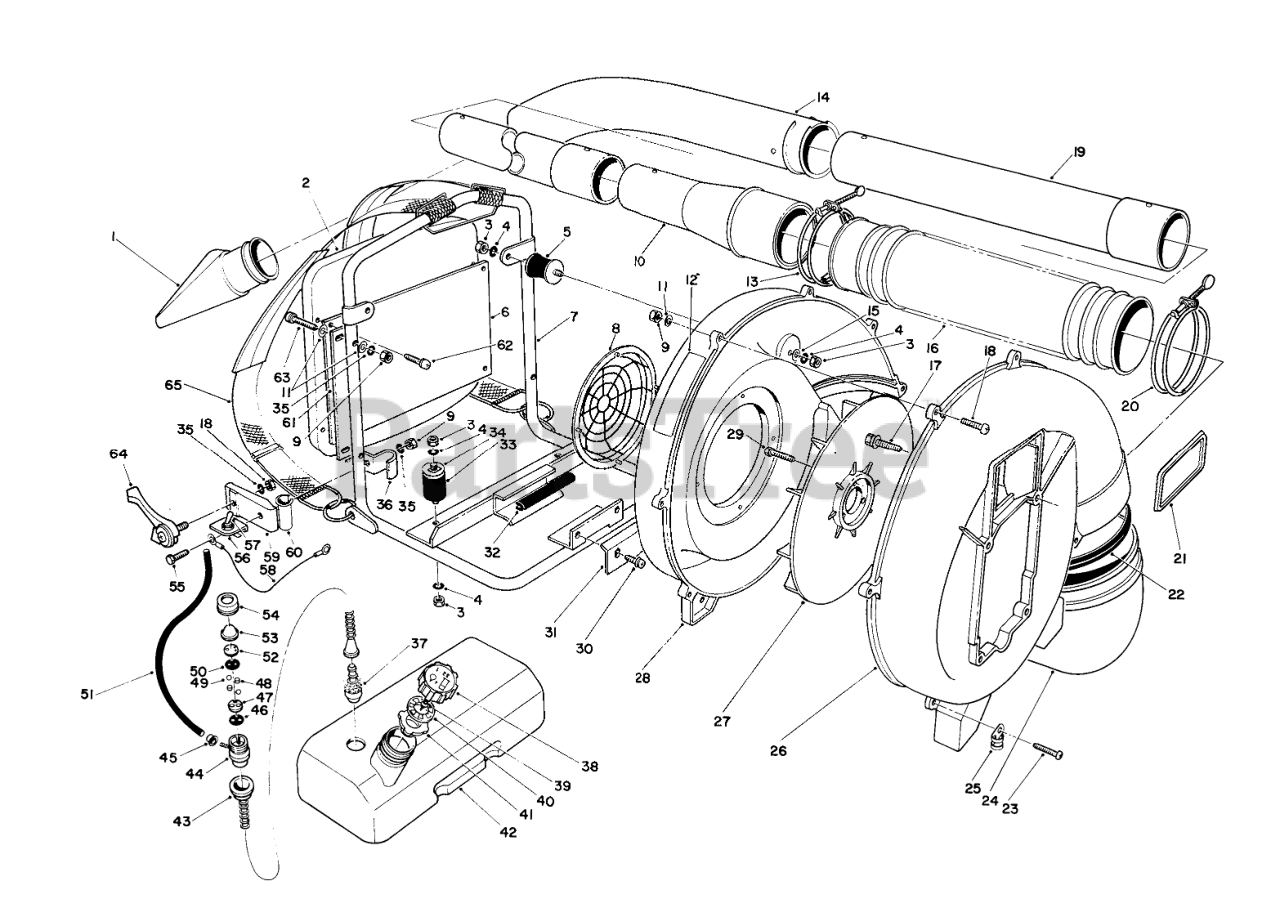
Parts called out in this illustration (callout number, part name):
1	NOZZLE
4	WASHER SPRING
5	CUSHION RUBBER
6	PLATE
7	FRAME
8	FAN COVER
11	WASHER
12	Decal-Warning
13	WIRE BAND
15	WASHER
16	Hose-Flexible
17	BOLT & WASHER
18	SCREW & WASHER
20	WIRE BAND
21	TORO LOGO PLT
22	DUST SEAL RING
23	SCREW
24	ELBOW
25	Clamp
26	FAN CASE
28	FAN CASE
29	BOLT ? WASHER
30	BOLT & WASHER
31	STOPPER
32	CUSHION RUBBER
33	CUSHION RUBBER
34	CUSHION HOLDER
35	SPRING WASHER
36	Stopper
37	FUEL FILTER
38	TANK CAP
39	BREATHER VALVE
40	HOLDER
41	GASKET - PACKING
42	Fuel Tank Assembly (Incl. Ref. #37-41, 43, 44, 46-50 & 52-54)
43	HOSE, SUCTION
44	Pump-Primer (Incl. Ref. #47-54)
46	GASKET
47	SEAT VALVE
48	SPONGE
50	GASKET
51	FUEL TUBE
52	SEAT VALVE
54	PUMP CAP
56	SWITCH BRACKET
57	STOP SWITCH
58	WIRE LEAD
59	Bracket
60	Bushing
61	PLATE
62	SCREW & WASHWER
63	SCREW & WASHER
64	THROTTLE LEVER
65	SHOULDER HARNESS
